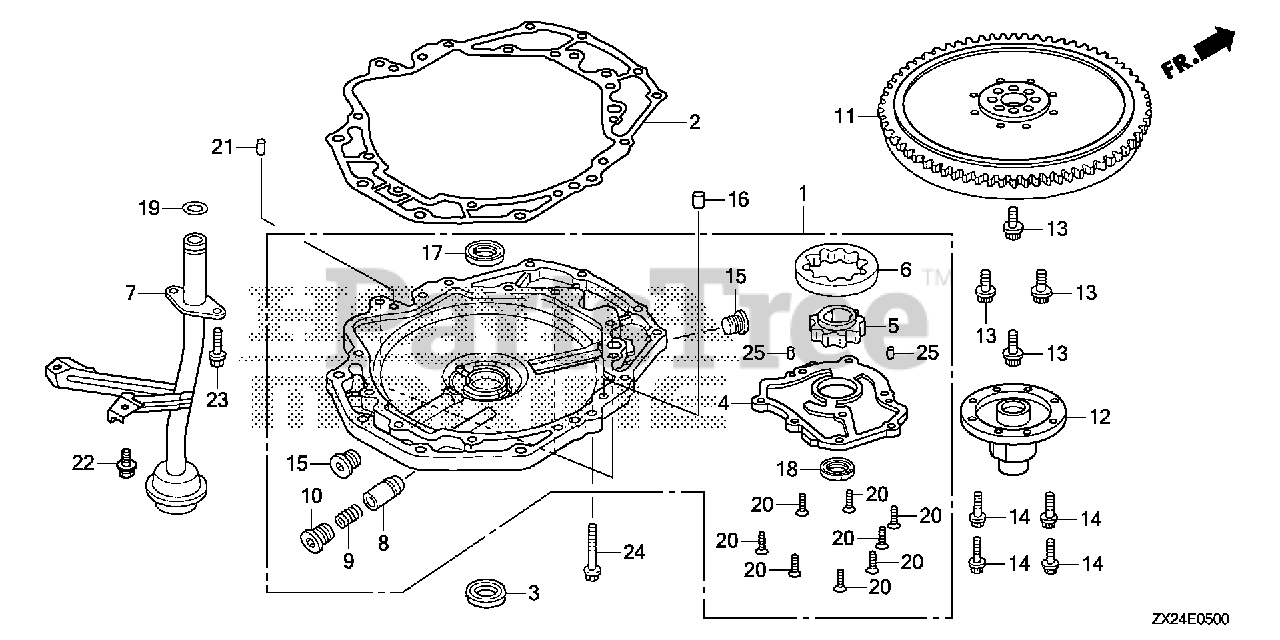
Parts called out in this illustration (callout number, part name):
1	PUMP ASSY., OIL *NH8* (DARK GRAY)
2	GASKET, OIL PUMP BODY
3	RUBBER, OIL PUMP
4	COVER, OIL PUMP
5	ROTOR, OIL PUMP (INNER)
6	ROTOR, OIL PUMP (OUTER)
7	STRAINER, OIL
8	VALVE, RELIEF
9	SPRING, RELIEF VALVE
10	BOLT, SEALING (18MM)
11	FLYWHEEL *TBLACK* (BLACK)
12	BOSS, FLYWHEEL
13	BOLT (12MM)
14	BOLT, SPECIAL (8MM)
15	BOLT, SEALING (22MM)
16	PIN, DOWEL (14X15)
17	OIL SEAL (46X60X9)
18	OIL SEAL (31X46X7) (NOK)
19	O-RING (20.6X2.6)
20	SCREW, FLAT (6X16)
21	PIN B, DOWEL (10X16)
22	BOLT, FLANGE (6X14)
23	BOLT, FLANGE (6X18)
24	BOLT, FLANGE (8X30)
25	ROLLER (5X8)
